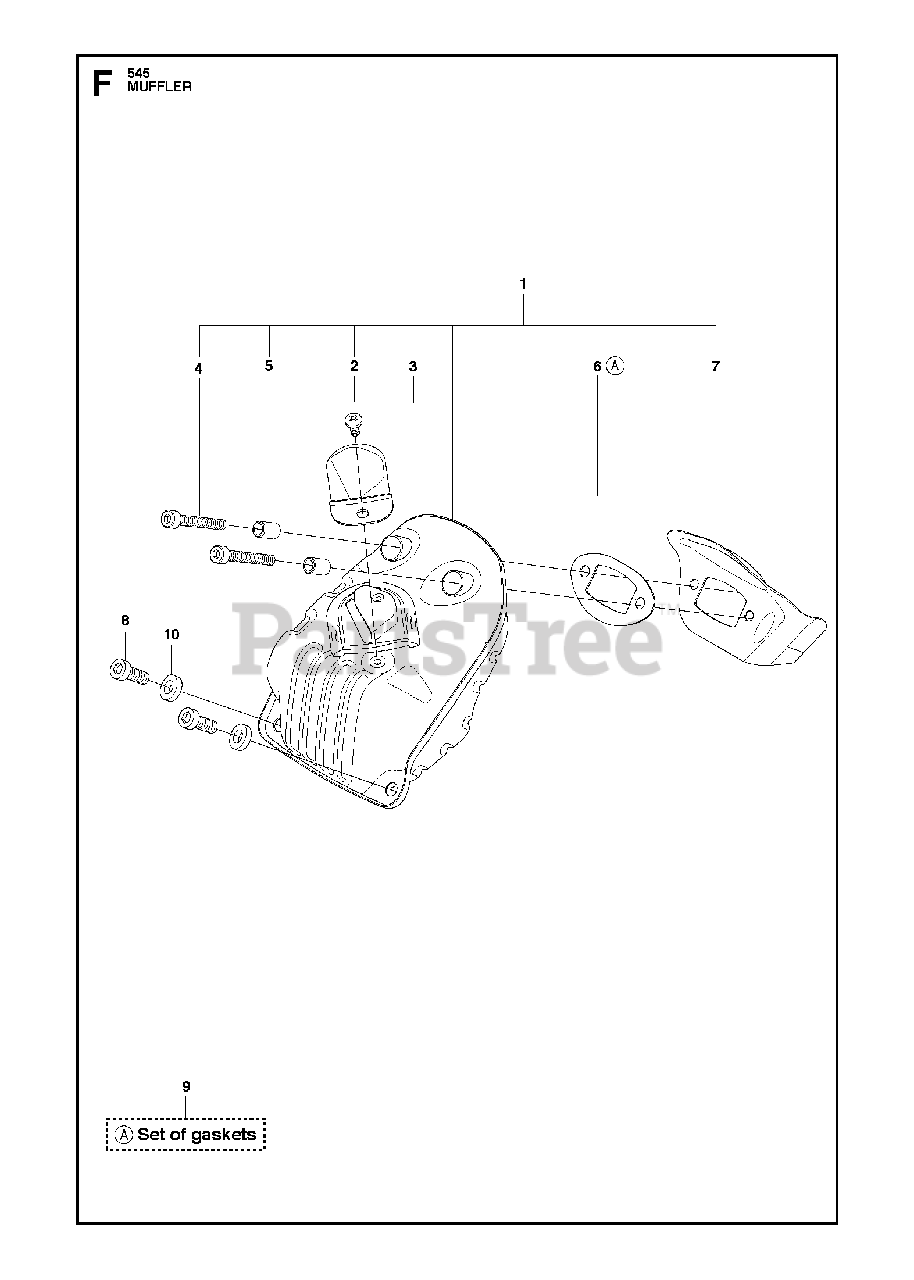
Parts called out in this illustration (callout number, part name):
1	MUFFLER KIT
2	SCREW
3	SPARK ARRESTER A004 50 CC
4	SCREW
5	SLEEVE
6	GASKET MUFFLER
7	HEAT DEFLECTOR
9	GASKET KIT
